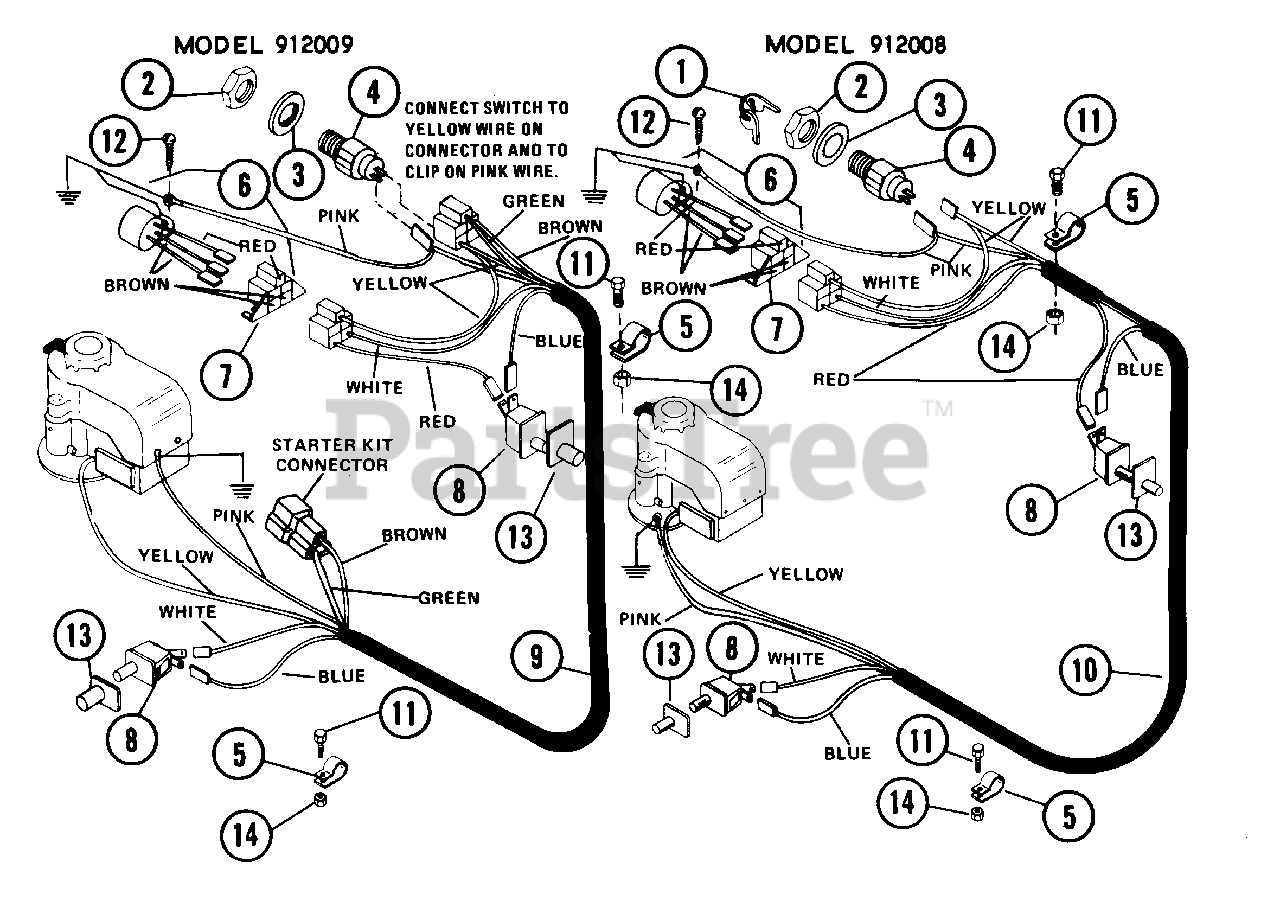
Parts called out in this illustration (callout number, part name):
1	KEYS
2	NUT .625-32 ALUM
3	WSHR-LK-INT .625X.045 PL
4	KEY SWITCH
6	MODULE T KIT
7	CONNECTOR
9	WIRING HARNESS
10	WIRING HARNESS
11	BLT-HEX .25-20X.50 PL GR2
12	SCR-TAP 10-12X.50 CRPH PL A
13	SWITCH BOOT
14	NUT-LK-CTR .250-20 PL
